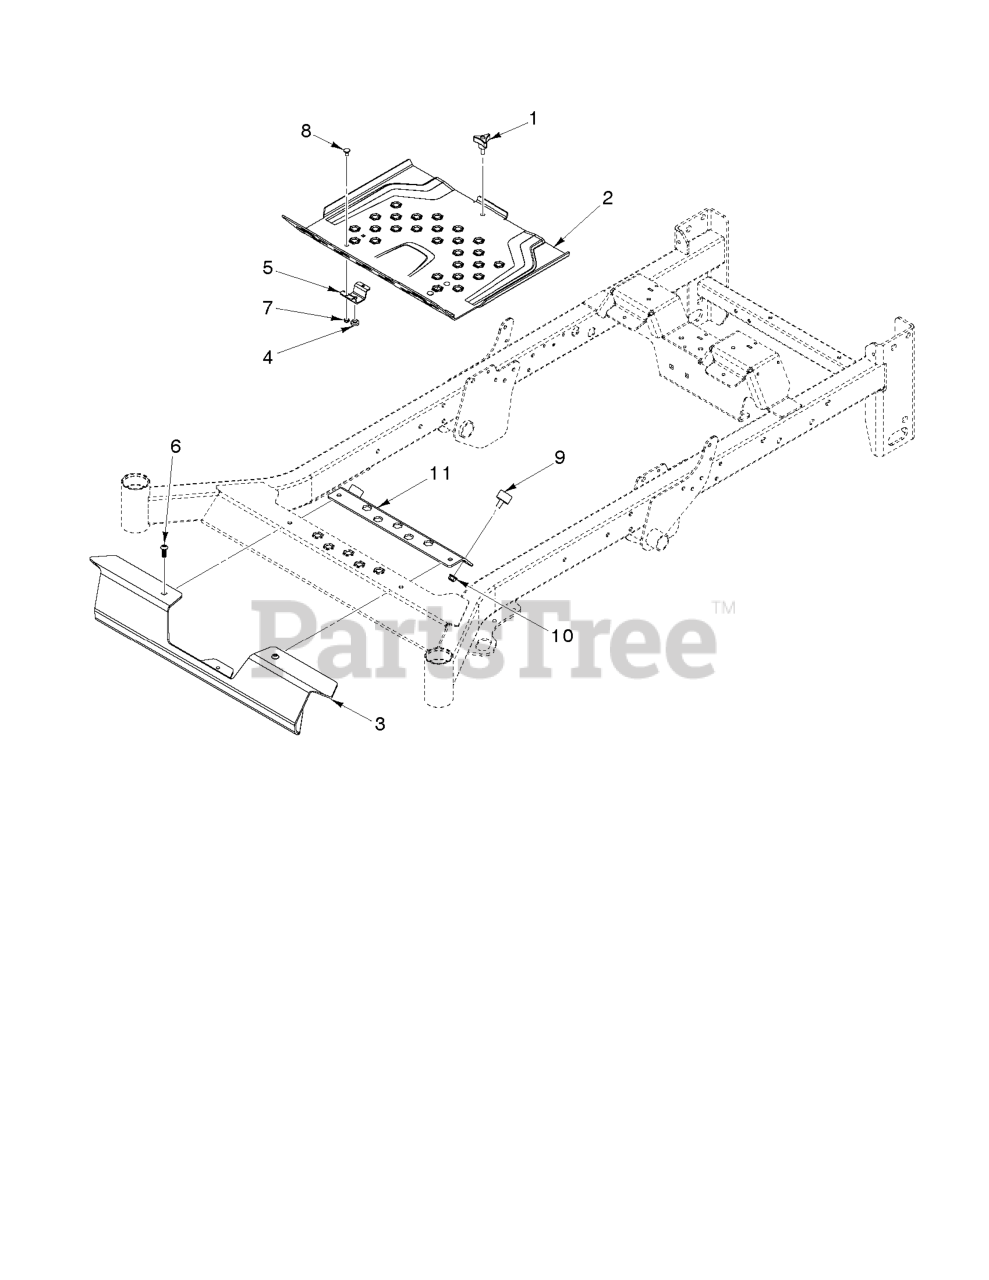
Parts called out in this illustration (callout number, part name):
1	KNOB W/STUD
2	PLATE.PNT.FOOTREST.PZ.ORANGE
3	COVER.PNT.VALANCE.PZ.GREY
4	GROMMET, BUMPER
5	COVER.PNT.VALANCE.PZ.GREY
6	SCREW.BUTTON.HEAD.TORX.3/8-161
7	JAM NUT 1/4C (2 2 PW01)
8	BOLT
9	ISOLATOR.PZ.FOOTREST
10	NUT 3/8-16 HEX FLG NYLOC ZD
11	BRACKET.PNT.ISOLATOR.SUPPT.BLK
